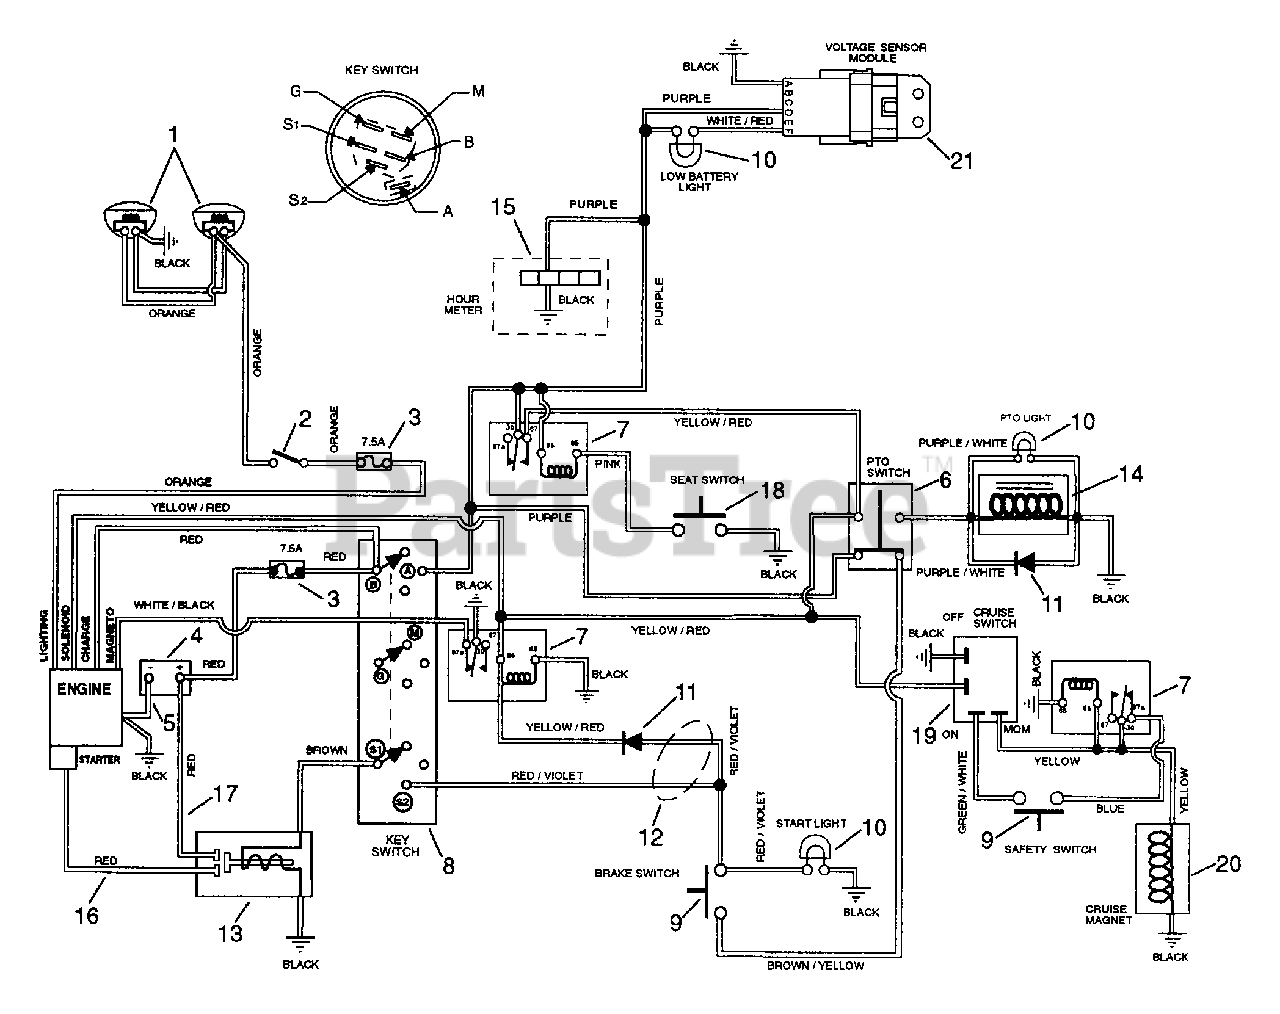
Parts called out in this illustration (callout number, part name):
1	HEADLIGHT- RH
2	SWITCH - LIGHT
3	7.5 AMP Fuse
4	BATTERY W/TUBE
5	GROUND CABLE .31X22.00X.31
6	PTO KNOB/ SWITCH ASSY
7	RELAY
8	KEY SWITCH
9	SWITCH- SINGLE POLE N.O.
10	#194 Bulb
11	MOLDED DIODE PLUG 1 AMP
12	WIRE HARNESS - 1440H B&S
13	SOLENOID
14	ELECTRIC CLUTCH/BRAKE(1.8AMP)
15	HOURMETER KIT- SIERRA
16	START CABLE 22"
17	STARTER CABLE 6.75"
18	SWITCH- SEAT
19	SWITCH - CRUISE
20	MAGNET
21	MODULE - VOLTAGE SENSOR
